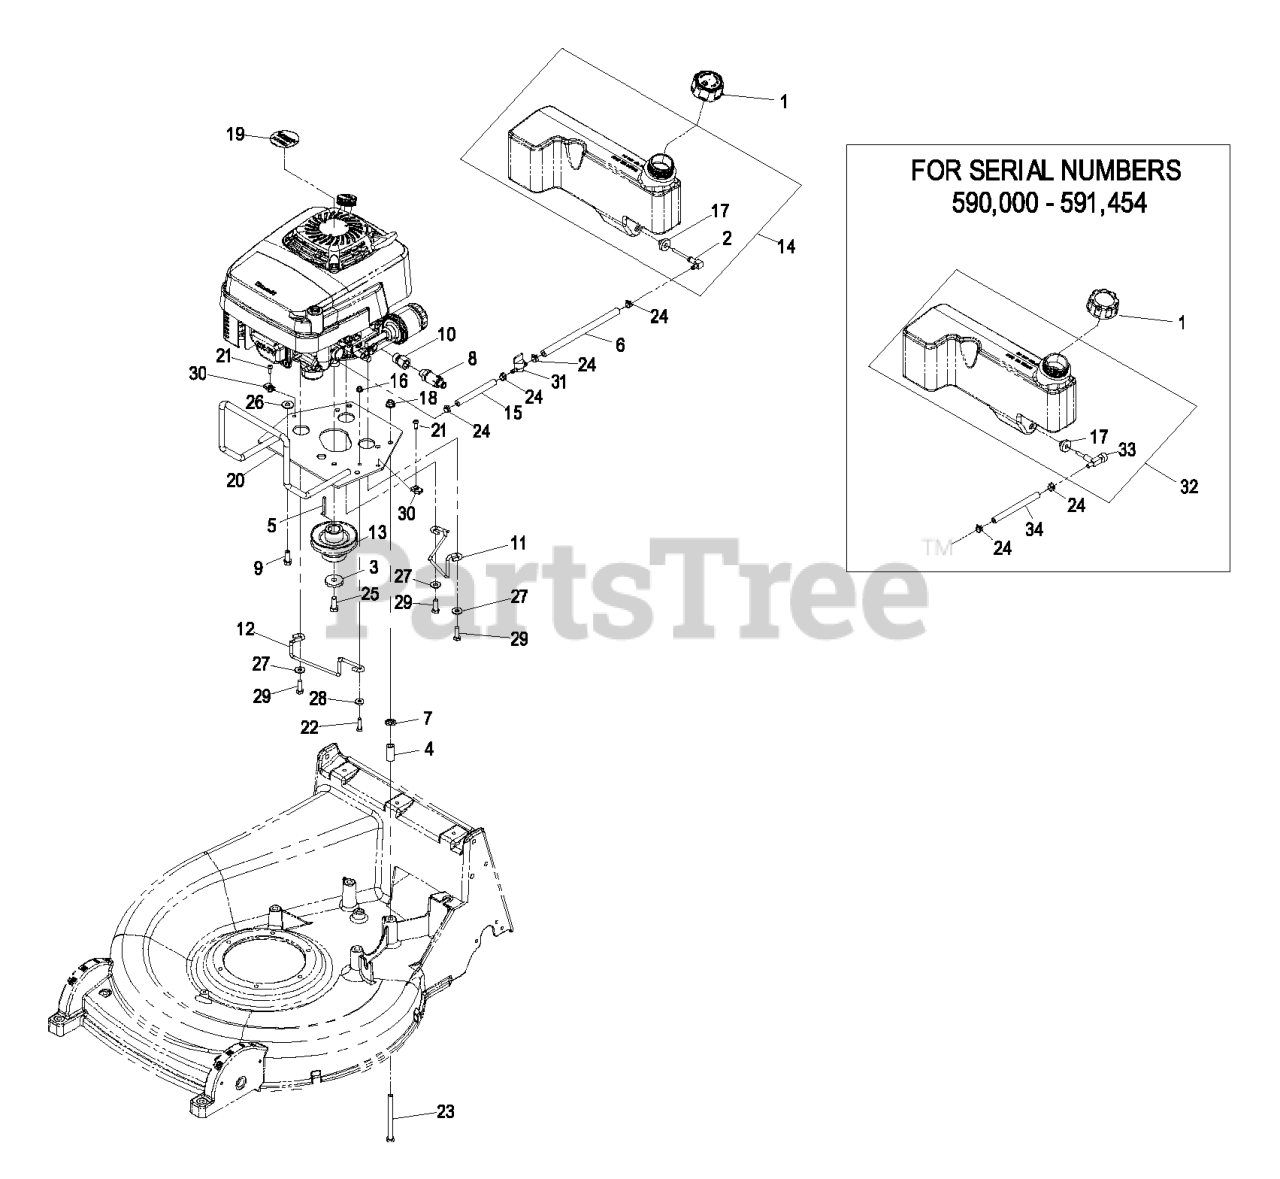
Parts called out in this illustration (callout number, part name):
1	CAP-FUEL
2	ELBOW-TANK, FUEL
3	WASHER-CLUTCH
4	BUSHING-LEVER, LIFT
5	KEY-SQUARE
6	HOSE-FUEL
7	RING-RETAINING
8	VALVE-DRAIN, OIL
9	SCREW-TAPTITE
10	ADAPTER
11	GUIDE-BELT, BLADE
12	GUIDE-BELT, TRANSMISSION
13	PULLEY-ENGINE
15	HOSE-FUEL
17	BUSHING
18	NUT-HF, NI
19	DECAL-RECOIL
22	SCREW-HH
23	SCREW-HH
24	CLAMP-HOSE
25	SCREW-HH
26	WASHER-FLAT
27	WASHER-FLAT
28	WASHER-FLAT
29	SCREW-HH
30	Nut, Retainer-Panel 1/4-20
31	VALVE-FUEL
32	ASM,FUEL TANK
33	VALVE-FUEL
